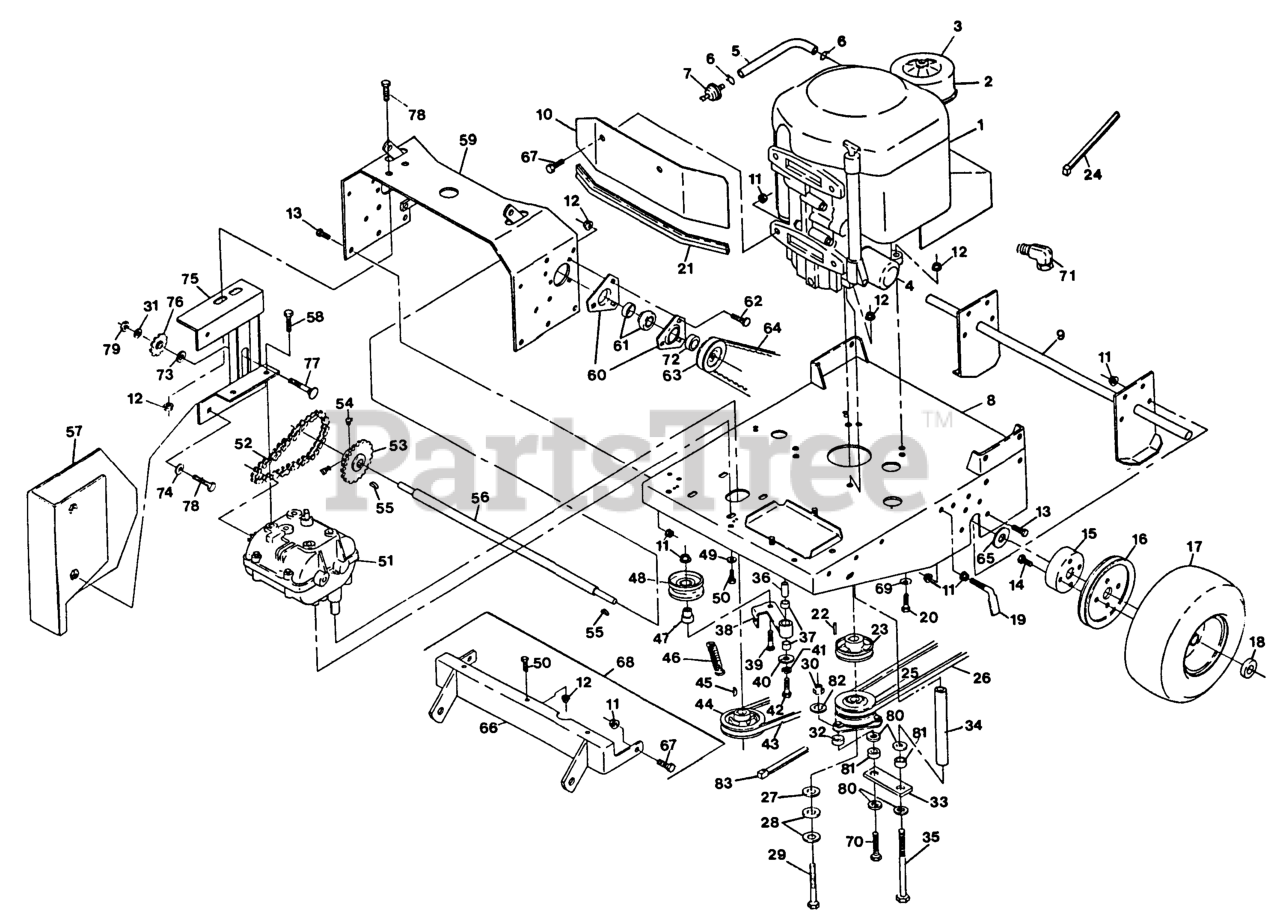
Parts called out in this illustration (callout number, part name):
5	HOSE-FUEL
10	SHIELD-HEAT, TRACER
14	SCRW,TPTTE HH
19	SCRAPER
24	TIE-CABLE
26	BELT,DECK DRIVE
27	BUSHING,CLUTCH KEEPER
28	WASHER-SPRING
35	SCREW-HH
36	BUSHING
37	SLEEVE-BEARING
46	SPRING-EXTENSION
47	BUSHING-IDLER
52	CHAIN-#40 ROLLER
60	HOUSING-FLANGE
64	BELT WHL CLTCH W-4.2
66	WLD,SULKY HITCH
68	Hitch - Tracer Sulky
69	WASHER-SPRING
71	FITTING-ELBOW-90
74	WASHER-LOCK
81	SPACER,CLUTCH ANCHOR
83	TIE-PLASTIC
